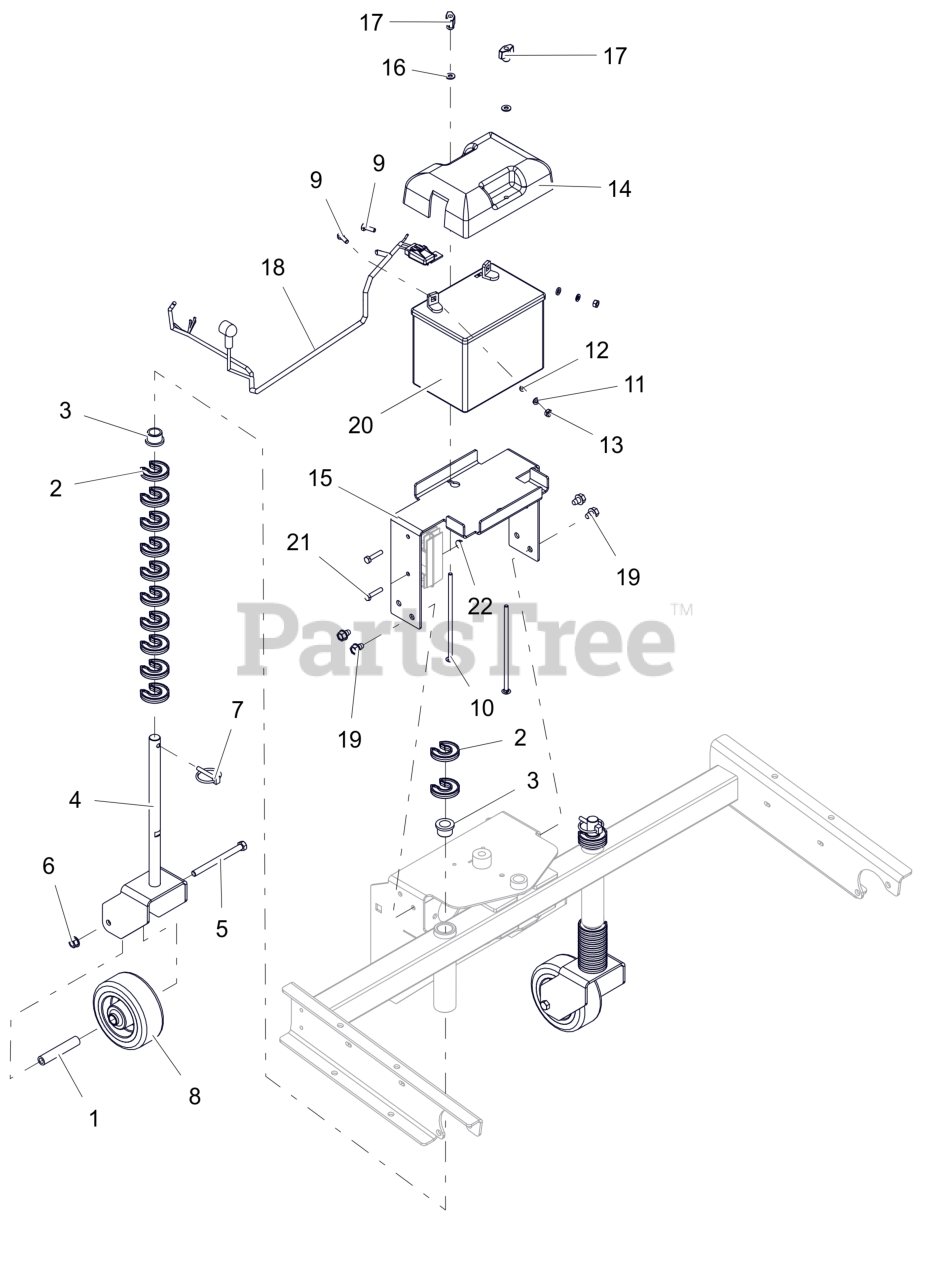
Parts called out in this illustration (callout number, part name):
1	SPACER, CASTER WHEEL
2	CLIP-HOC FIXED
3	BUSHING, FLANGE .75X.75X1.0
4	FORK, CASTER
5	BLT, HEX 0.375-16X4.5 GR5 ZCC
6	NUT-LK-TOP-FLG .38-16 ZC120
7	PIN, LYNCH .25X1.562 ZCC
8	WHEEL, CASTER - 5"OD
9	BLT, HEX .25-20X.75 G5 ZCC
10	BLT,RHSN .25-20X7.00 G2 ZCC
11	WSHR,LK-REG .250X.062 ZCC
12	WSHR,FLT .265X.500X.087 ZCC
13	NUT-STD .250-20 G2 ZCC
14	COVER, BATTERY
15	TRAY, BATTERY - POWER BRUSH
16	WSHR,FLT .281X.625X.065 ZCC
17	KNOB, WING - .25-20 UNC
18	HARNESS, ELECTRIC 12V BRUSH
19	SCR,TAP .375-16X.50 HWH TR ZCC
20	BATTERY, 300 CCA 10U1L
21	BLT, HEX .25-20X1.25 G5 ZCC
22	NUT-LK-TOP-FLG .250-20 GF ZCC
